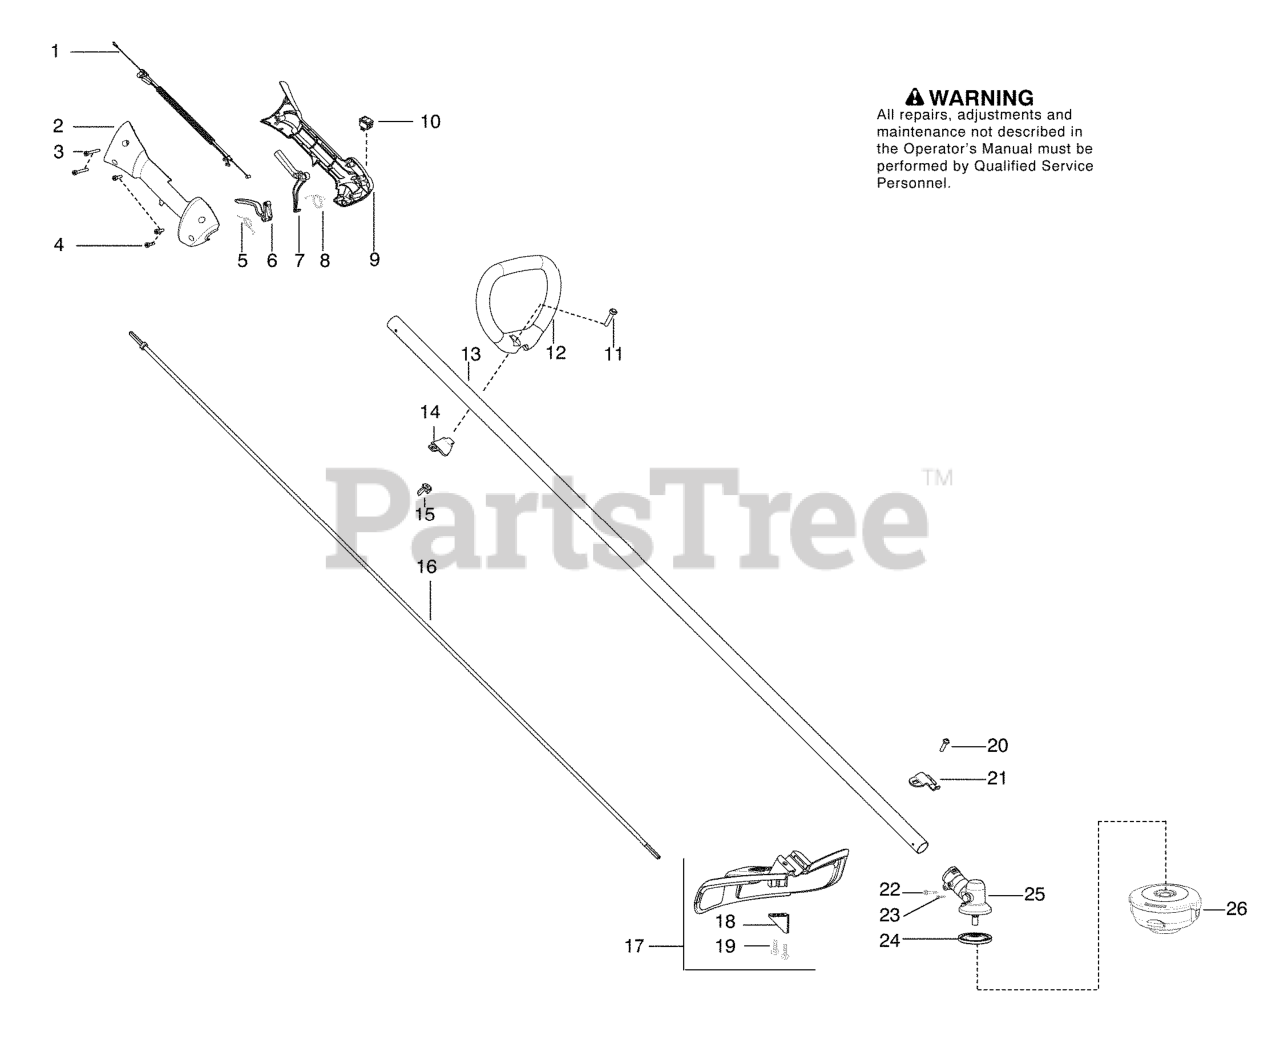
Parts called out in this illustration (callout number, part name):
1	Assy-Cable/Wire Harness
2	HOUSING-THROTTLE RH
4	SCREW M4 X 1.75 PT 16MM
5	SPRING TRIGGER
6	TRIGGER THROTTLE
7	THROTTLE LOCKOUT
8	SPRING LOCKOUT
9	HSG THROTTLE LH
10	KIT SWITCH
11	BOLT, TYPE 2
13	KIT DRIVESHAFT SST
14	CLAMP ASSIST HANDLE
15	WINGNUT, TYPE 2
16	Flex shaft
17	KIT COBI SHIELD
18	Limiter-Line
20	SCREW 1/4-20 X 7/8 (TAP
21	BRACKET SHIELD STRAIGHT SHAFT
22	SCREW - CARB. ADAPTOR
24	DRIVE DISC
25	ASSY GEARBOX
26	T25 10MM LH TRIMMER HEAD
